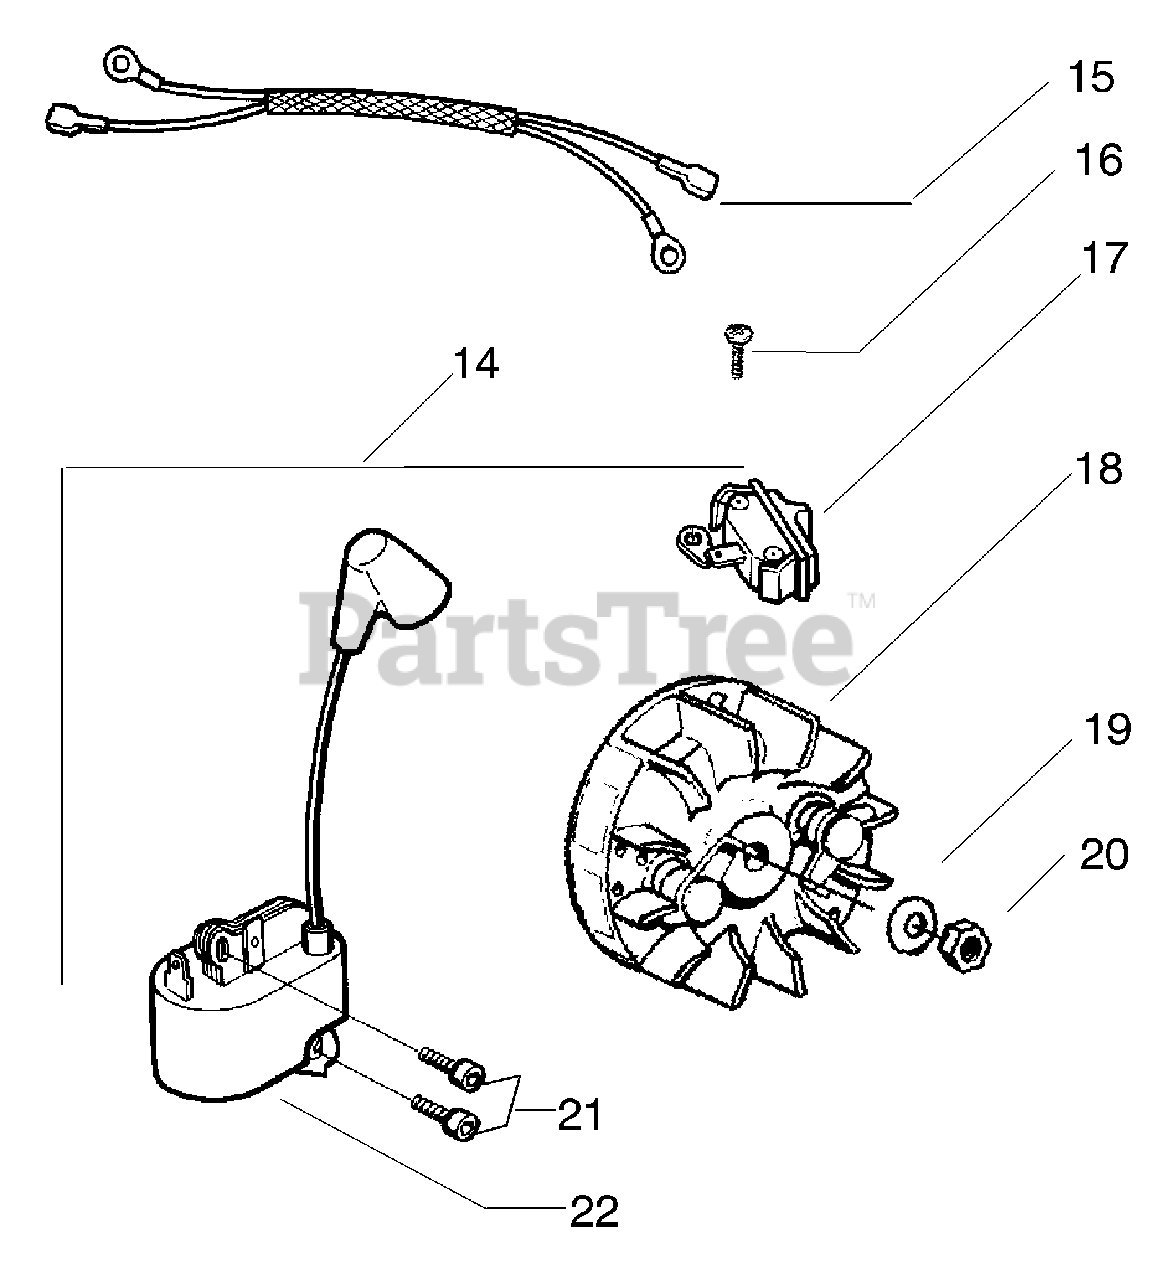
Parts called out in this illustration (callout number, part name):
14	Kit-EPS ignition
15	Assy-Leadwire
17	Switch-Ignition
18	Assy. -Flywheel
19	Washer-Flywheel
22	Module - Ignition
